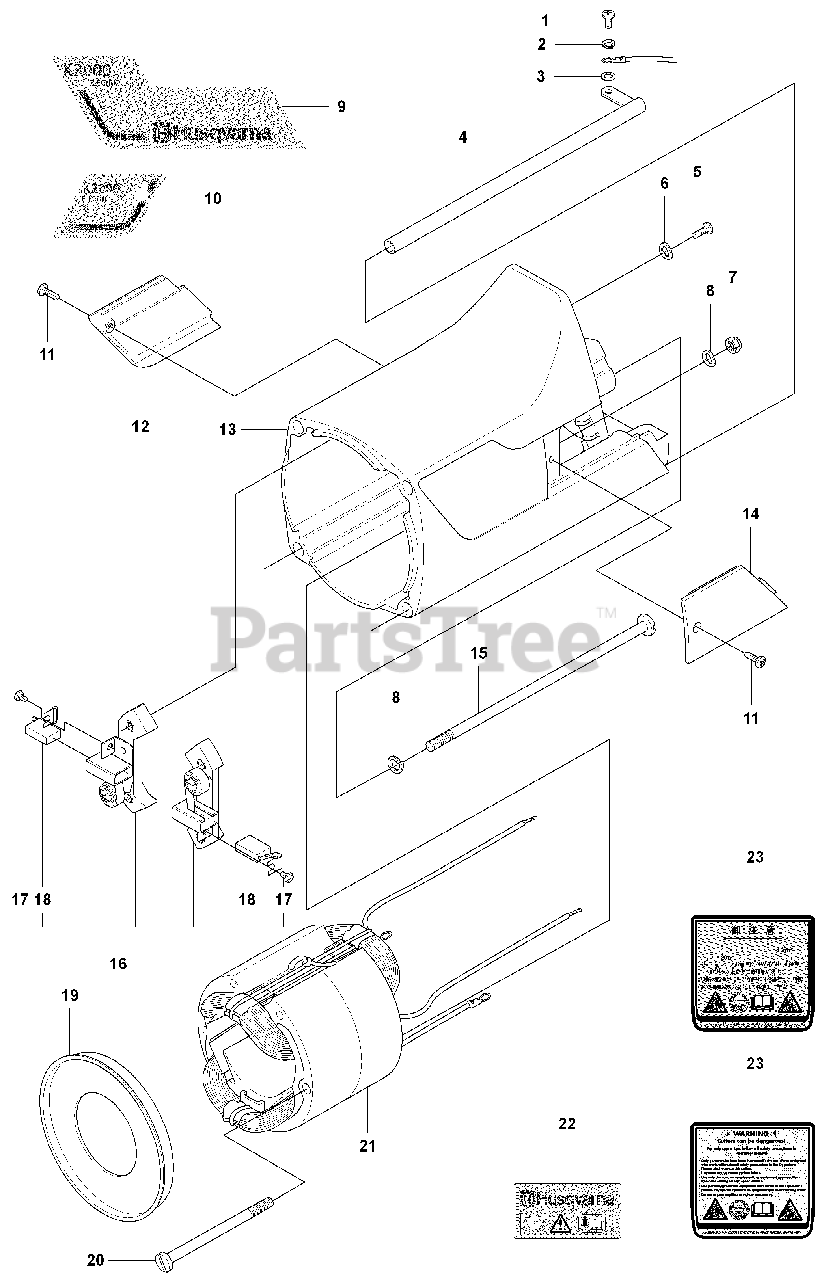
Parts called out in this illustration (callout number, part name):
13	MOTOR HOUSING
16	BRUSH ROCKER
17	CARBON BRUSH
19	AIR STREAM DIRECTOR
21	FIELD COIL
22	LABEL WARNING
23	LABEL
